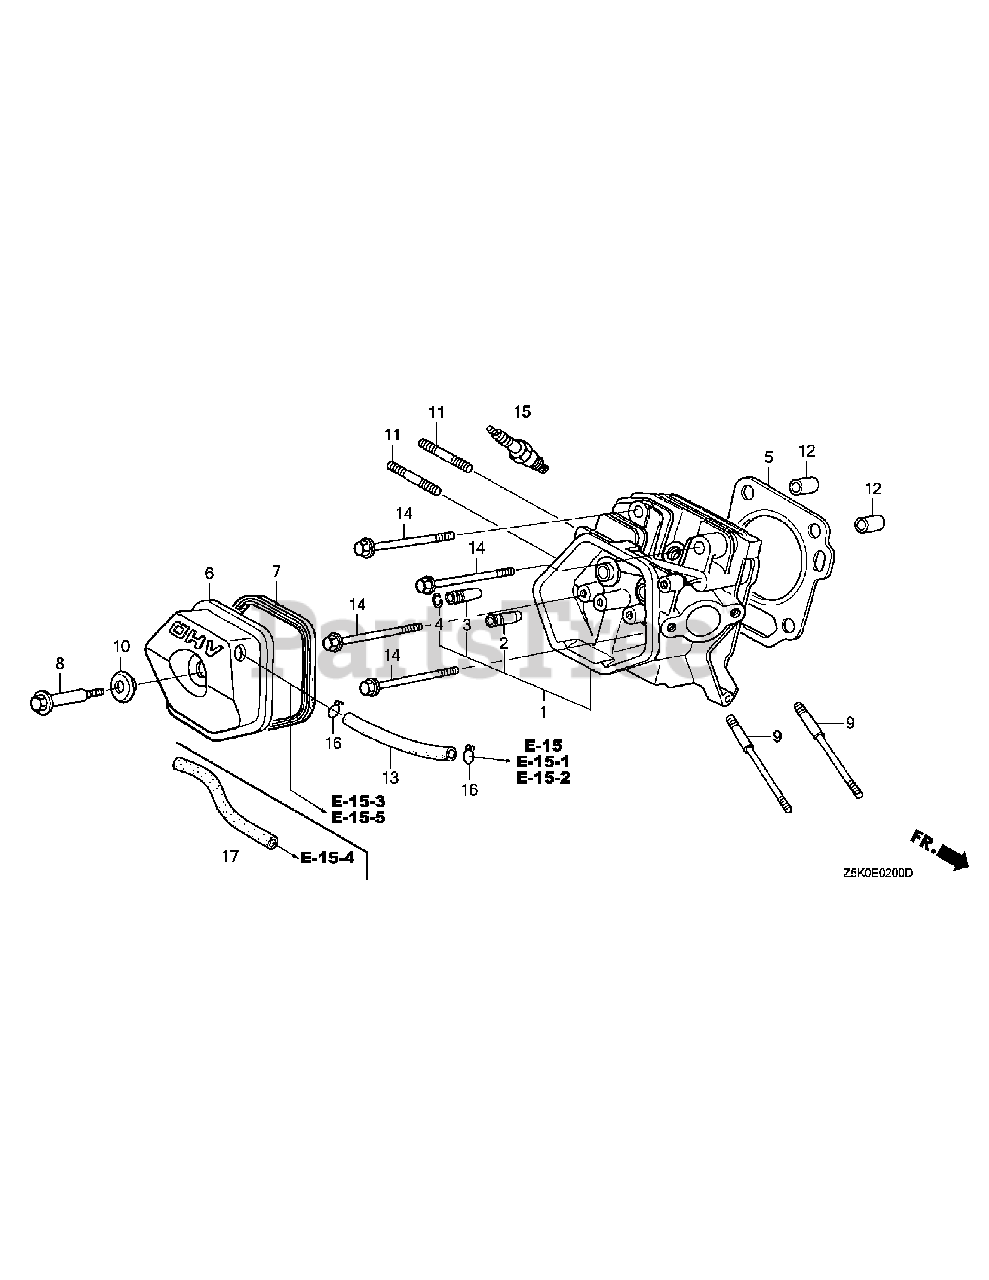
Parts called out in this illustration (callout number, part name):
1	Head Comp., Cylinder
2	Guide, In. Valve(O.S.)
3	Guide, Ex. Valve(O.S.)
4	Clip, Valve Guide
5	Gasket, Cylinder Head
6	Cover, Cylinder Head
7	Packing, Head Cover
8	Bolt, Head Cover
9	Bolt, Stud, 8X123
10	Washer Comp., Head Cover
11	Bolt, Stud, 8X32
12	Dowel Pin, 12X20
13	Tube, 11X100(95005-11001-30M)
14	Bolt, Flange, 10X80
15	Plug, Spark(Bpr6Es)(Ngk)
15	Plug, Spark(Bpr5Es)(Ngk)
16	Clip, Breather Tube
17	Tube, Breather
